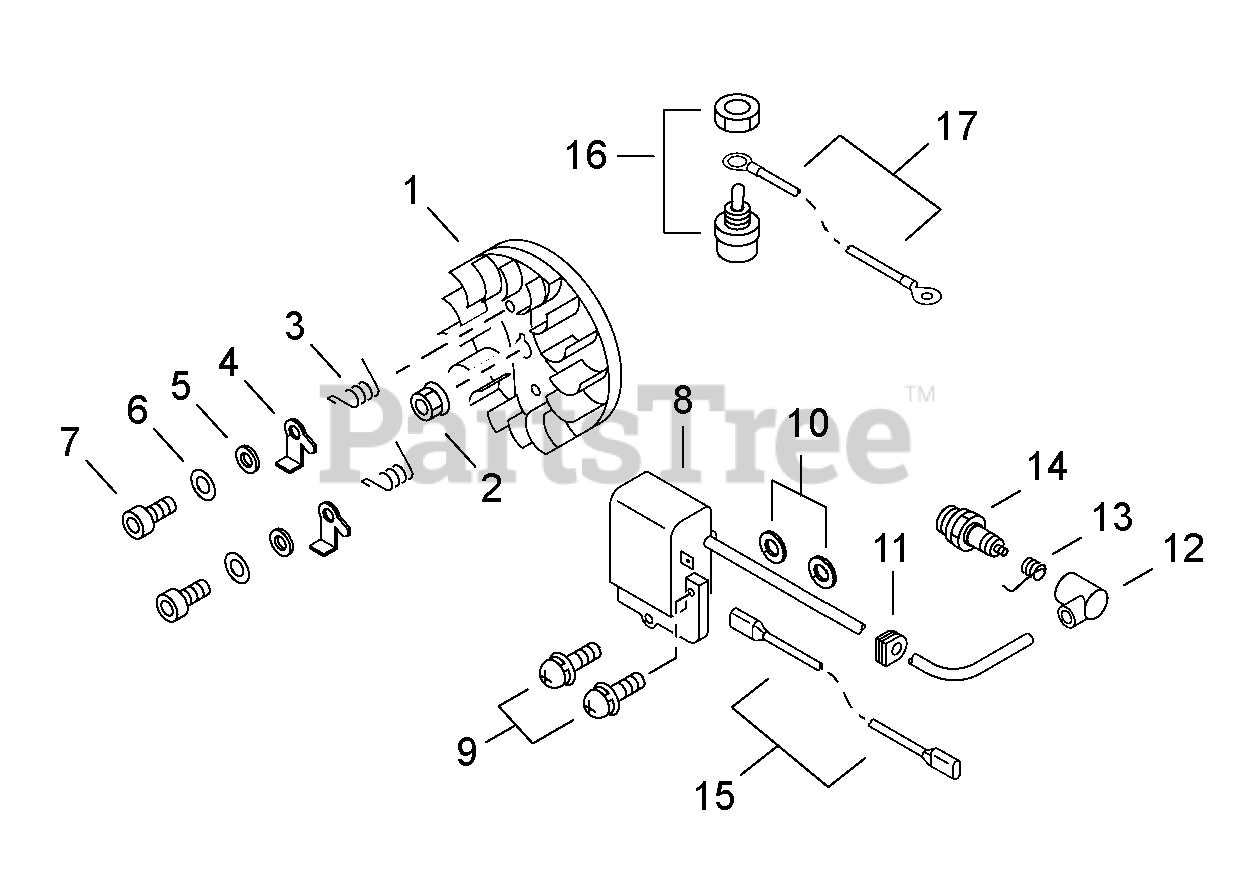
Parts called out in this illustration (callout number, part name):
1	FLYWHEEL
2	NUT - 8 -- FLANGE
3	SPRING, RETURN
4	PAWL, STARTER
6	WASHER - 5
7	SCREW - 5X14
8	COIL, IGNITION
9	SCREW - 5X22
12	CAP, SPARK PLUG
13	TERMINAL, SPARK PLUG CAP
14	SPARK PLUG -- BPM-7A
15	LEAD - IGNITION
16	SWITCH, IGNITION
17	LEAD - GROUND
